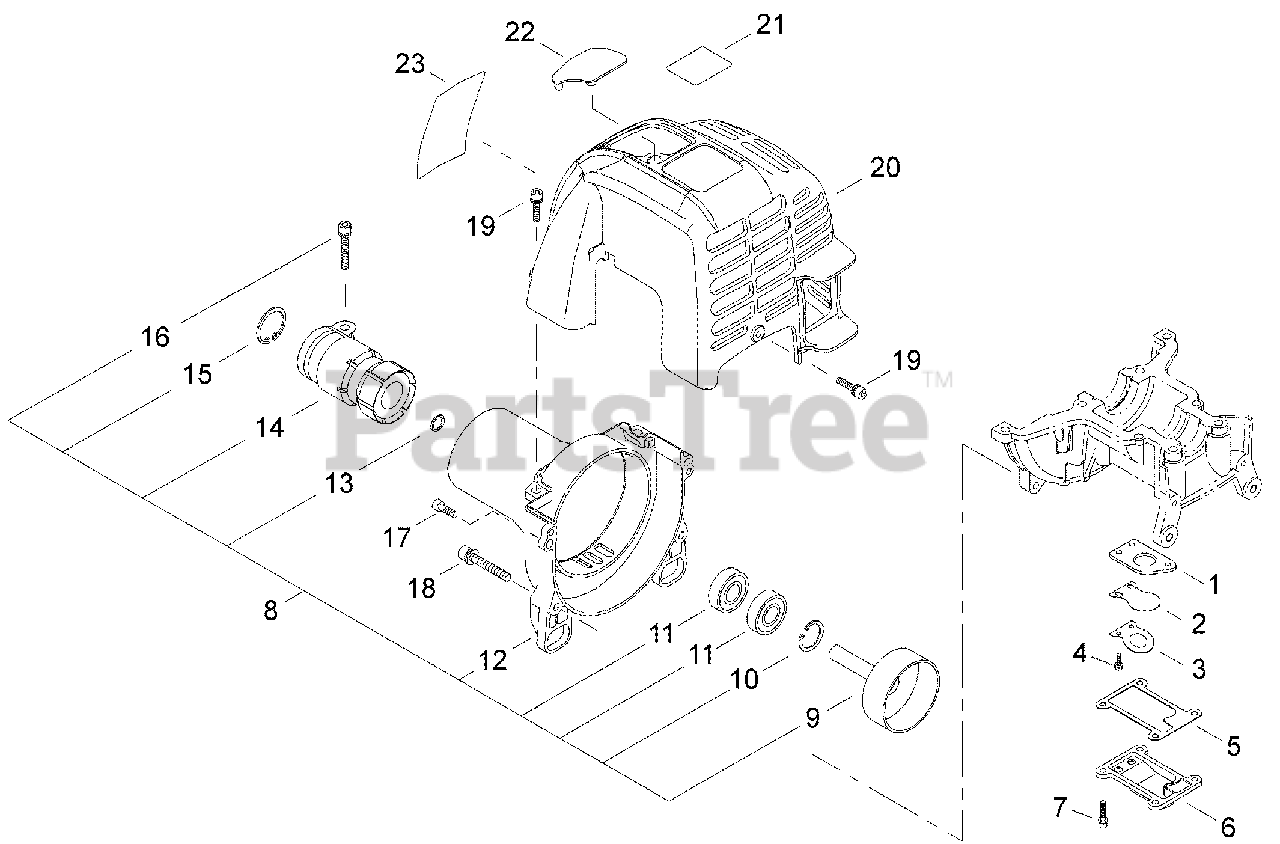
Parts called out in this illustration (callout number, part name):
1	PLATE, REED BACKING
2	VALVE, REED
3	STOP, REED VALVE
4	SCREW M3×10
5	GASKET, REED VALVE
6	COVER, REED VALVE
7	BOLT M4×14
8	COVER ASSY, FAN
9	DRUM, CLUTCH
10	RING, SNAP Ø28
11	BEARING, BALL 6001 DDU C3
12	COVER, FAN
13	RING, SNAP Ø12
14	CUSHION, AV
15	RING, SNAP Ø42
16	BOLT M5×22
17	BOLT 5×16
18	BOLT M5×40
19	BOLT M4×14
20	COVER, ENGINE
21	LABEL, E4 S4000
22	COVER, SPARK PLUG
23	LABEL, SWISHER E4
